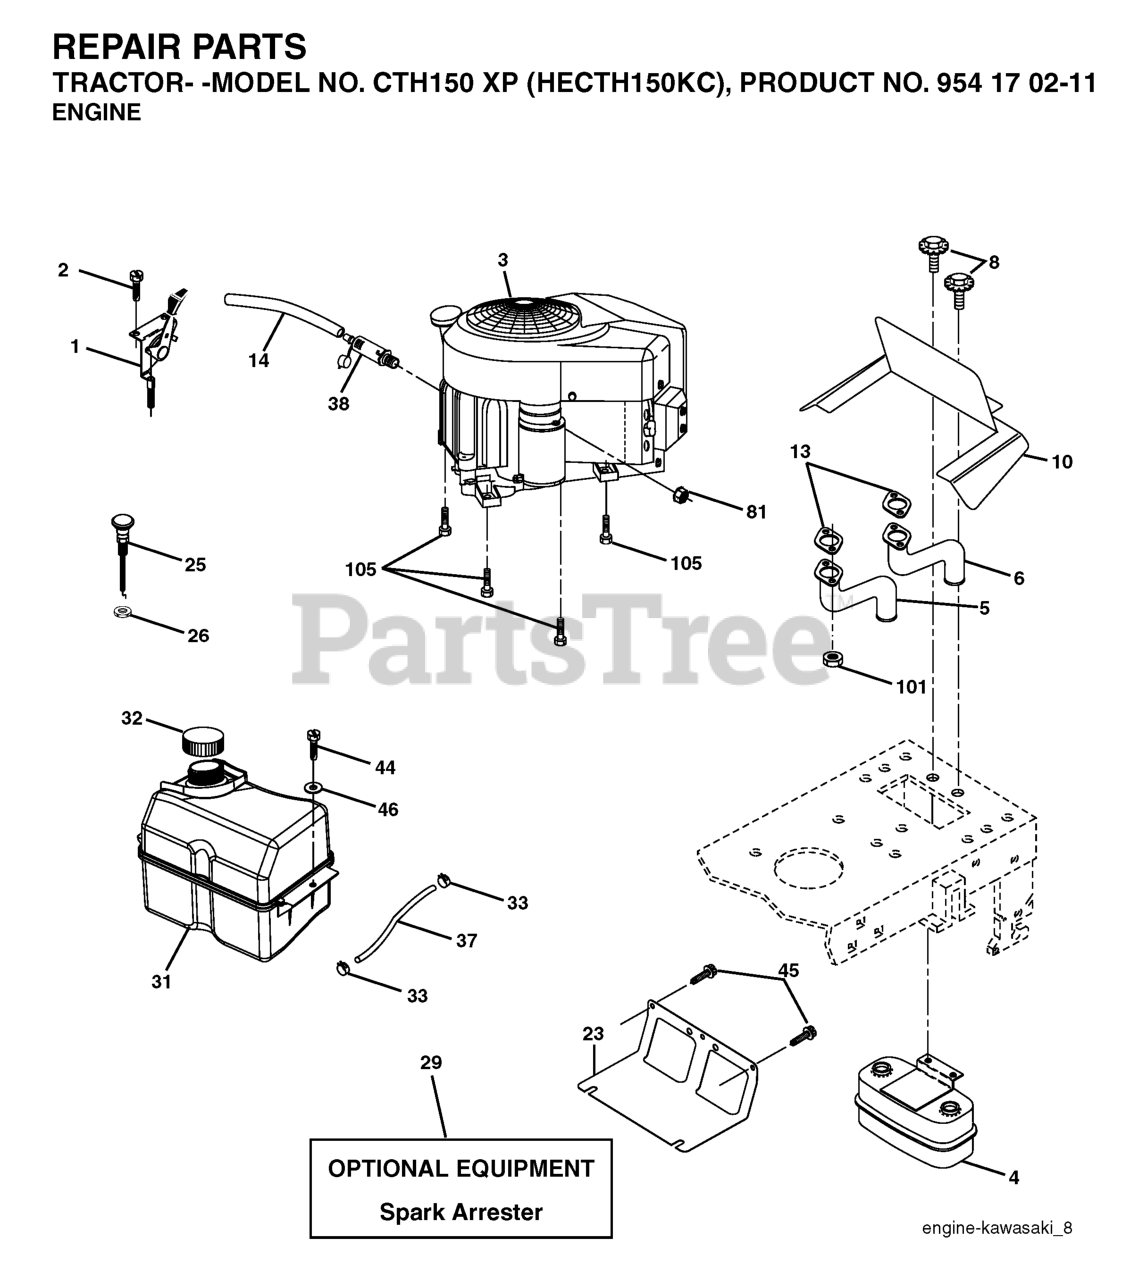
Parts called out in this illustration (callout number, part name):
1	CONTROL, THROTTLE
2	SCREW
4	MUFFLER.TWIN.CYL.LOW.TONE
5	EXHAUST TUBE LH KAWI
6	EXHAUST TUBE RH KAWI
8	BOLT.5/16-18UNCX3/4 W/SEMS.BLK
10	RP SHIELD HEAT MUFFLER
14	TUBE, DRAIN OIL ASM.
23	SHIELD.BROWNING.DBR.GUARD
29	KIT.SPARK ARRESTOR 794945 B&S
31	FUEL TANK
32	FUEL CAP
33	HOSE CLAMP
37	LINE.FUEL.20
44	SCREW HEXWSHR 1/4-20X3/4
45	SCREW, 3/8-16X3/4
81	NUT
101	NUT.HEX.FLANGE.TOPLOCK
105	SCREW 3/8-16X1
